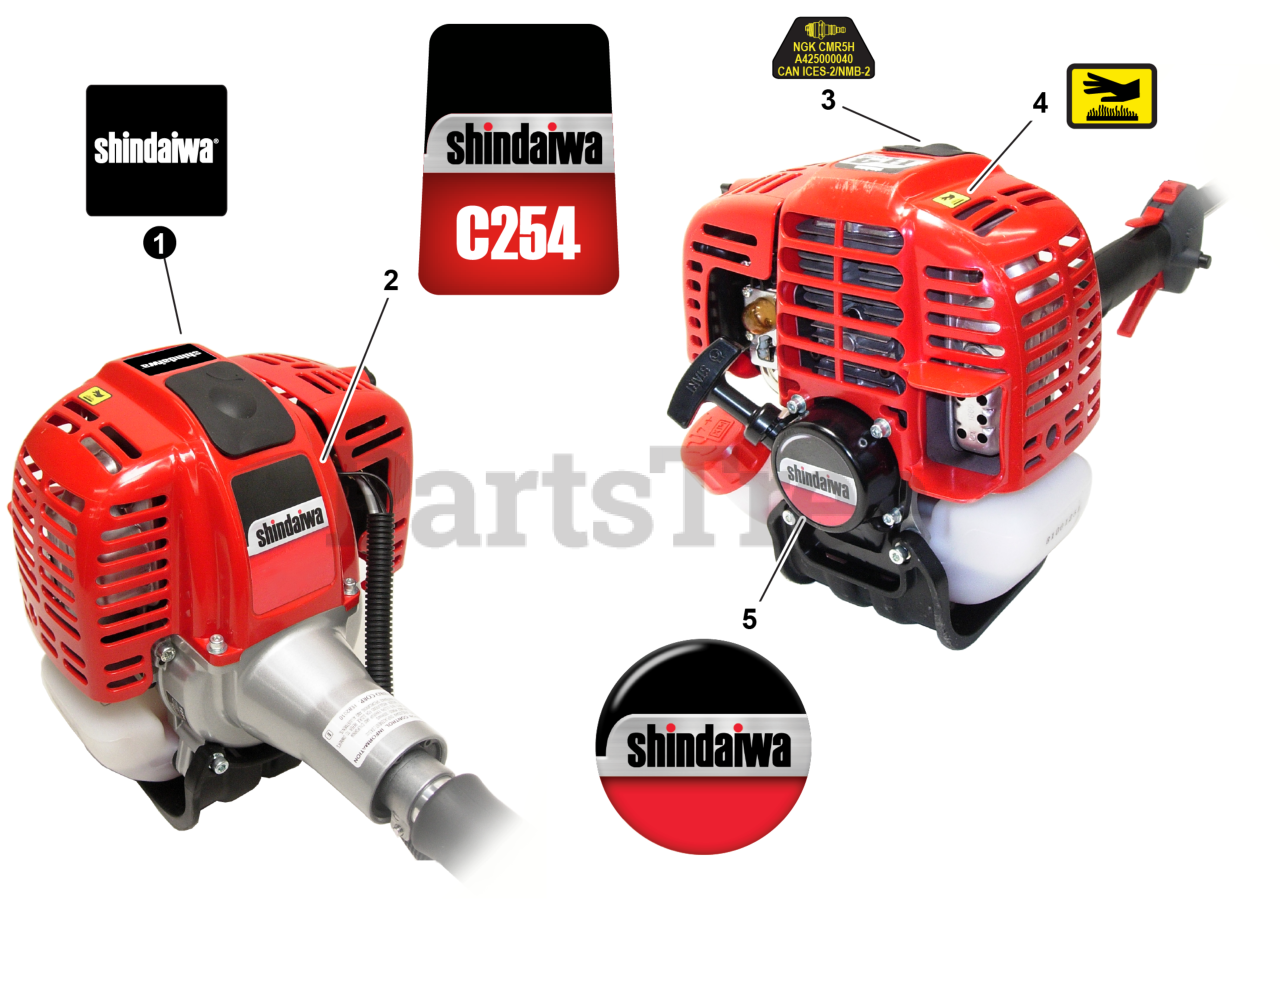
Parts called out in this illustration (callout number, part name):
1	LABEL - SHINDAIWA
2	LABEL - C254
3	LABEL - SPARK PLUG - CMR5H
4	LABEL - CAUTION - HOT
5	LABEL - RECOIL STARTER
